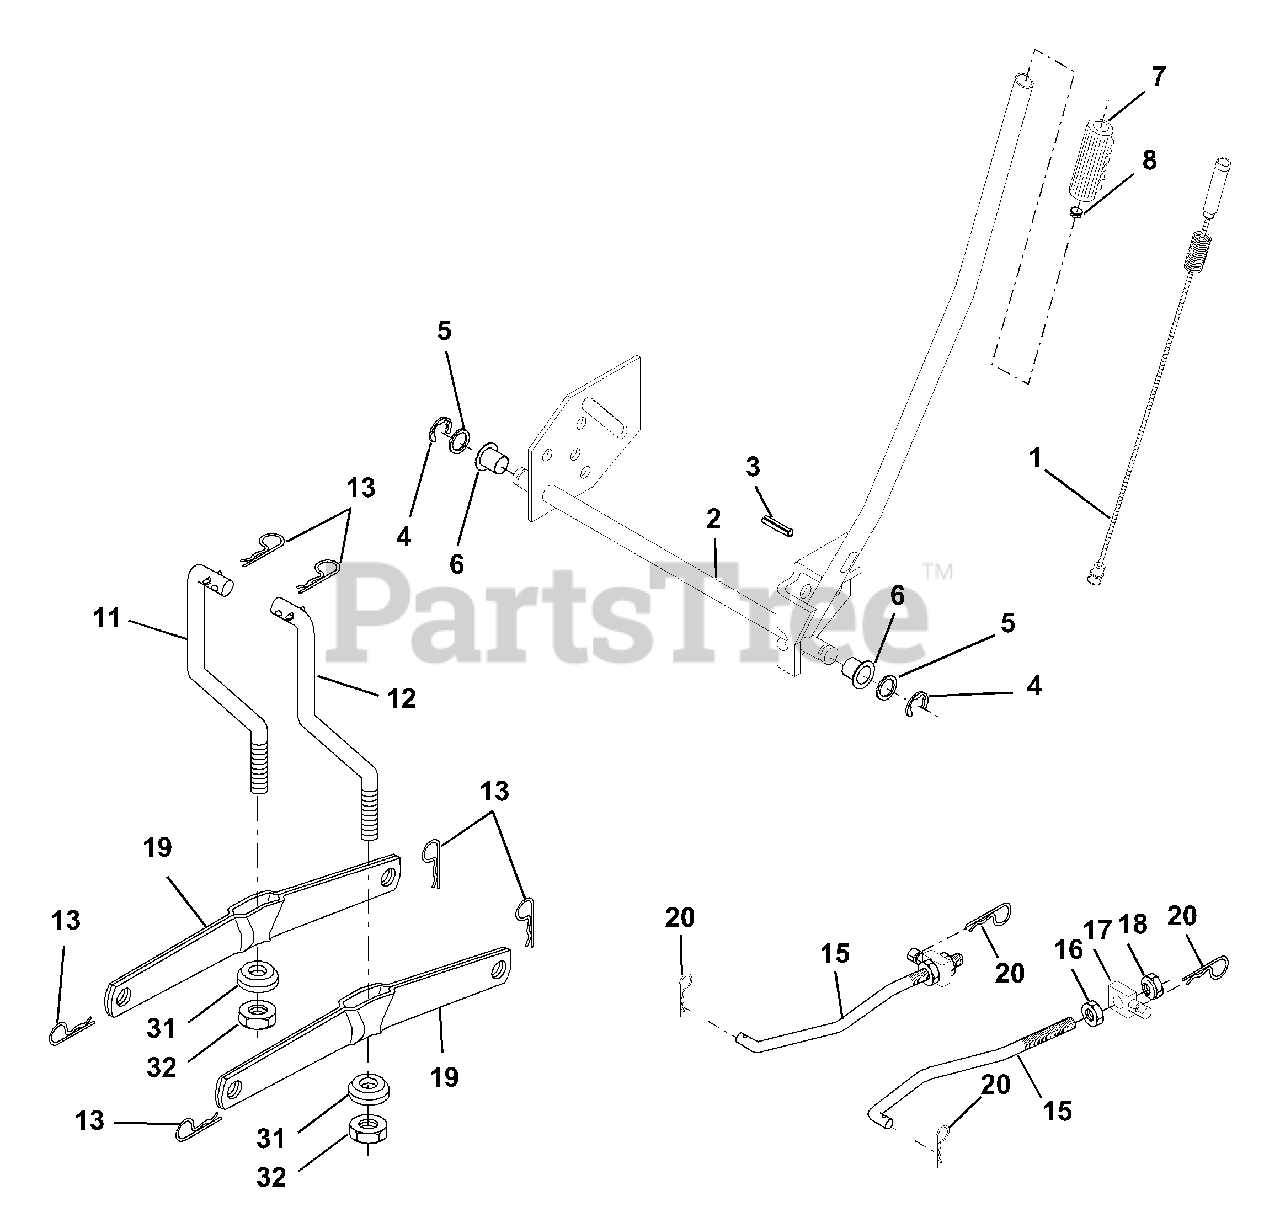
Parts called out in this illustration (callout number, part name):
1	Wire Asm Inner W/plunger
2	Shaft Asm Lift
3	Pin Groove
4	E Ring #5133-62
5	Washer PLTD 21/32 X 1 X 21ga
6	Bearing Nylon Blk 629 Id
7	Grip Handle Bicycle
8	Button Plunger Black
11	Link Lift LH
12	Link Lift RH
13	Retainer Spring
15	Link Front
16	Nut Jam Hex 1/2-13 Unc
17	Trunnion Blk Zinc
18	Nut Crownlock 1/2-13 Unc
19	Arm Suspension Rear
20	Spring, Retainer
31	Bearing Pvt. Lift Spherical
32	Nut Crownlock 3/8-24
